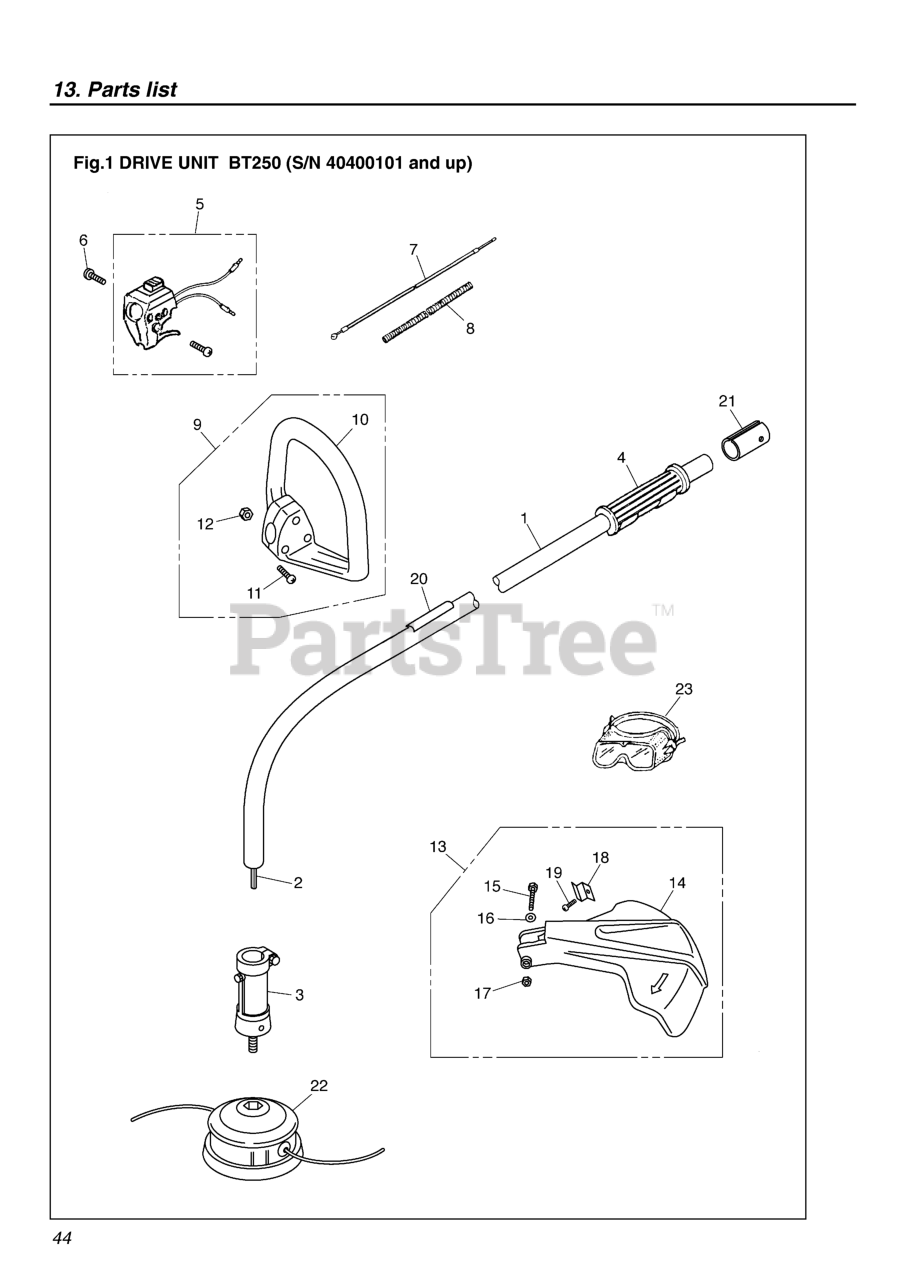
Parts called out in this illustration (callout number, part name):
1	PIPE COMP
2	DRIVE SHAFT (54
3	HOUSING ASSY.
5	LEVER ASSY.
7	CABLE COMP (RPLS 1633-83100)
9	HANDLE ASSY.
11	SCREW, M5 x 30
13	GUARD ASSY.
20	PLATE NAME
22	TAP HEAD
23	GOGGLE
